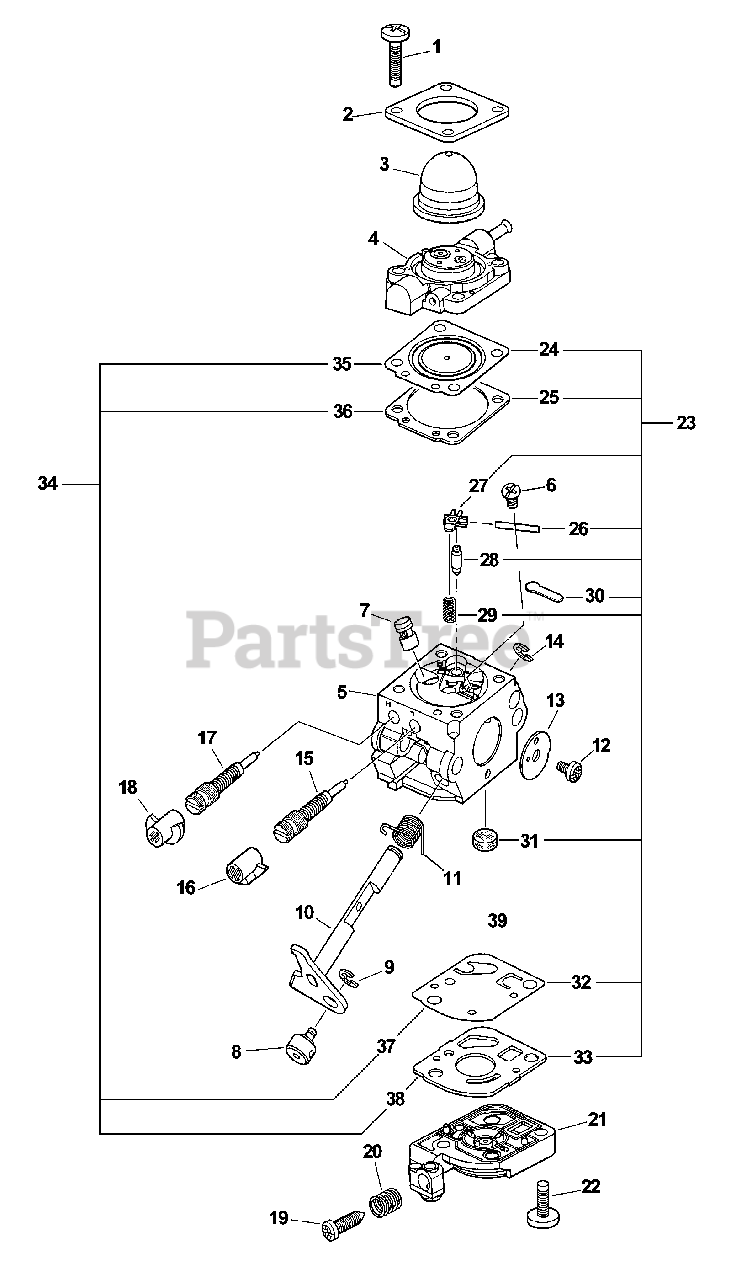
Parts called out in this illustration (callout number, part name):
2	RETAINER, PURGE BULB
3	BULB, PURGE
4	BODY ASSY, PURGE
5	BODY, CARBURETOR
6	SCREW
7	NOZZLE, CHECK VALVE
10	SHAFT ASSY, THROTTLE
11	SPRING, THROTTLE RETURN
13	VALVE, THROTTLE
15	NEEDLE, MIXTURE
16	CAP, LIMITER - WHITE
17	NEEDLE, HIGH SPEED
18	CAP, LIMITER - RED
19	SCREW, THROTTLE ADJUST
21	COVER, FUEL PUMP
23	REBUILD KIT
24	DIAPHRAGM, METERING
25	GASKET, METERING
26	PIN, METERING LEVER
27	LEVER, METERING
28	VALVE, INLET NEEDLE
29	SPRING, METERING LEVER
30	PLUG, WELCH
31	STRAINER
32	DIAPHRAGM, PUMP
33	GASKET, PUMP
34	GASKET / DIAPHRAGM KIT
35	DIAPHRAGM, METERING
36	GASKET, METERING
37	DIAPHRAGM, PUMP
38	GASKET, PUMP
